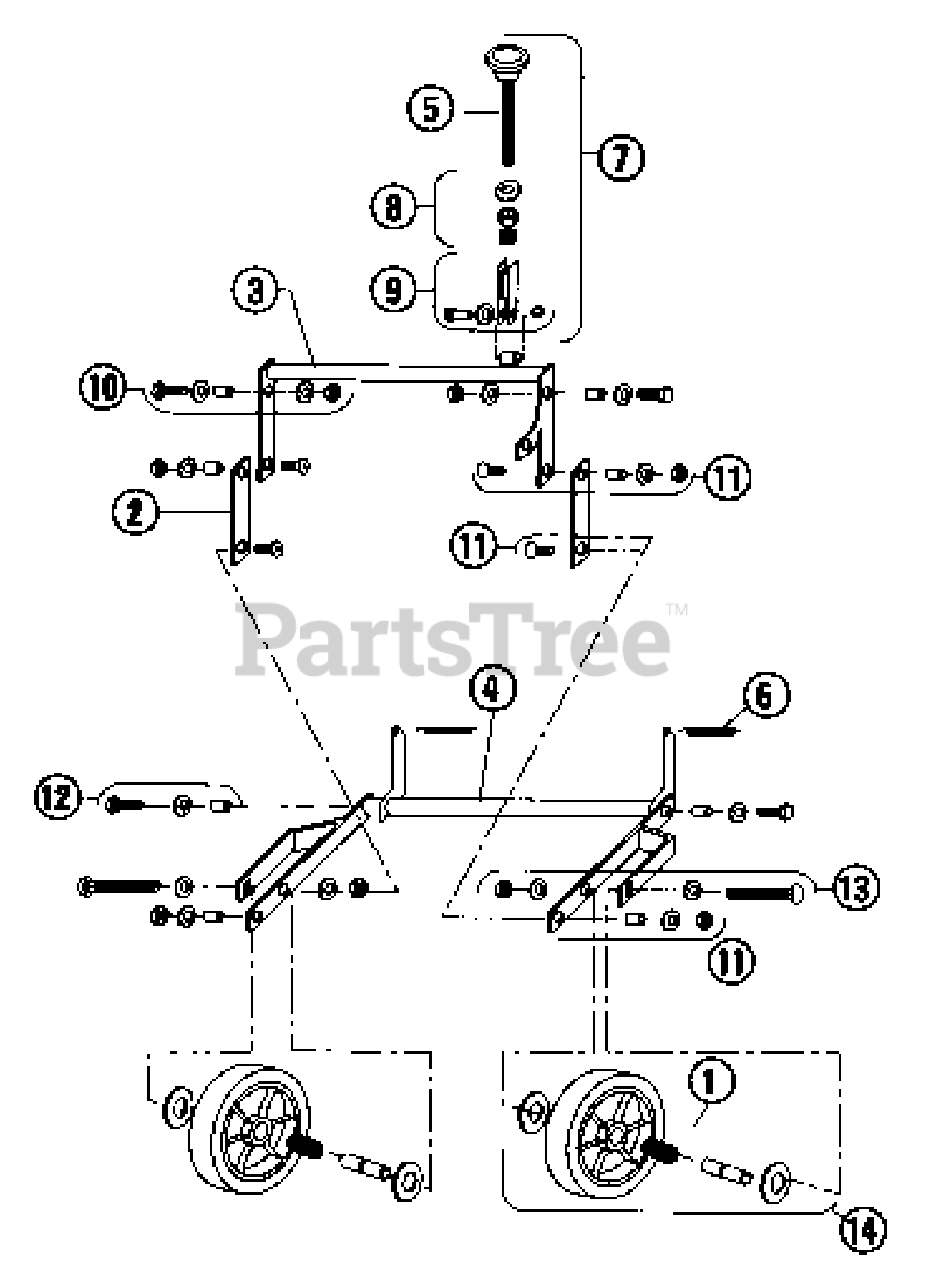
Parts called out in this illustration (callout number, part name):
1	Bearing, roller with bushing and seals
3	Torque arm, depth adjustment
4	Wheel carriage, axle
5	Knob, depth/stability
6	Spring, axle
7	Control kit, depth/stability
8	Knob spring kit, depth/stability
9	Bracket kit, depth/stability
10	Fastener kit, torque arm/housing
11	Fastener kit, linkage
12	Fastener kit carriage/housing
13	Bolt kit, rear wheel
14	Wheel kit, rear, with roller bearing, bushing and seals
